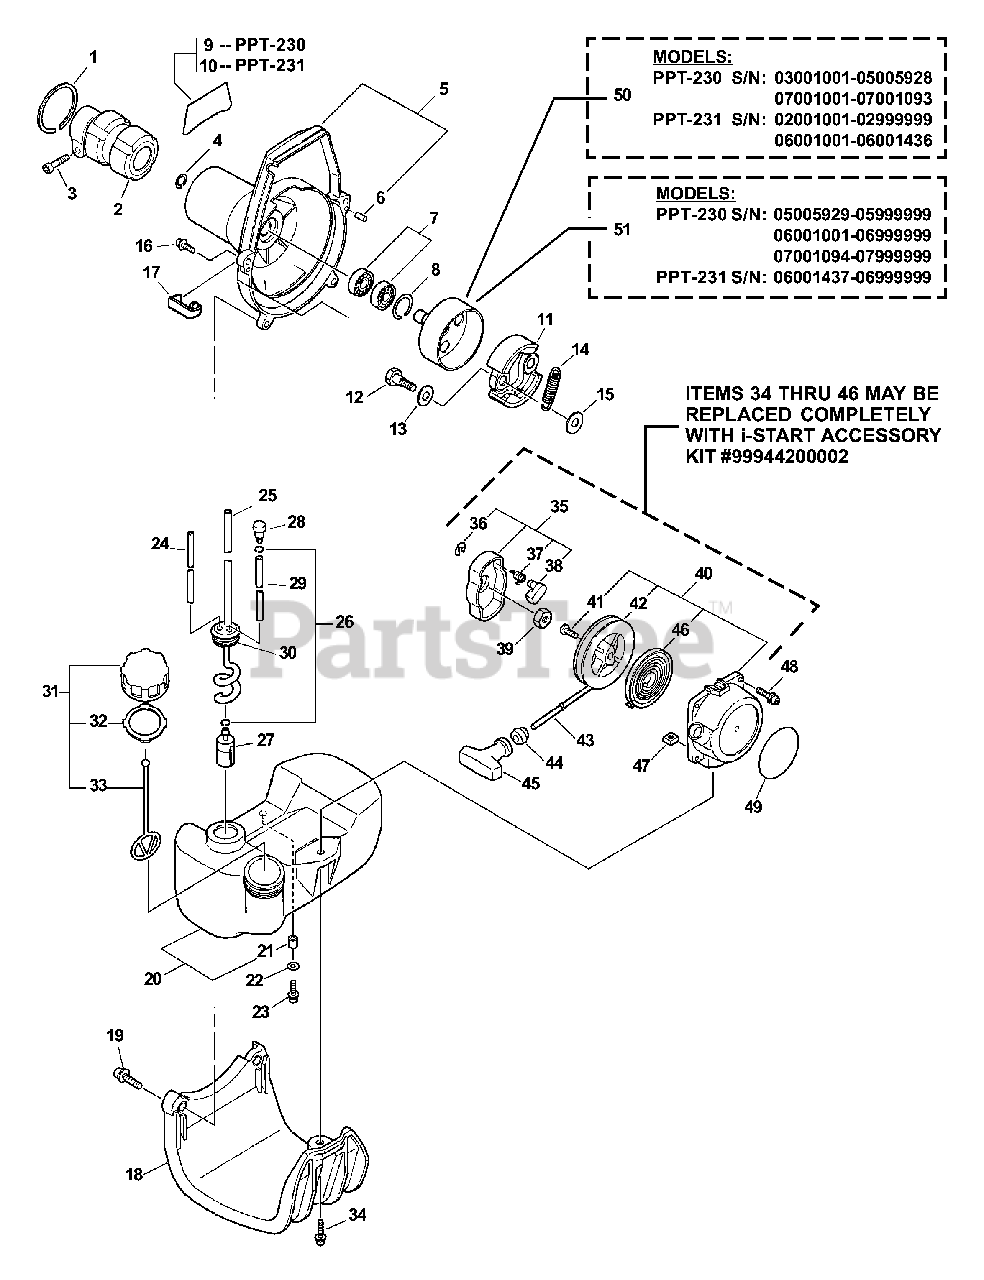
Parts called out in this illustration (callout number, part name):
1	RING, SNAP Ø42
2	HOLDER, MAIN PIPE
3	BOLT 5×28
4	RING, RETAINING - 12
5	FAN CASE ASSY - ORANGE
6	PIN, LOCATING 4
7	BEARING, BALL 6001
8	RING, SNAP 28
9	LABEL, MODEL
10	LABEL, MODEL
11	SHOE, CLUTCH
12	BOLT, CLUTCH 8×7.9×M6
13	WASHER, SPRING 8.5×16×0.5
14	SPRING, CLUTCH
15	WASHER 6.2×19×1.0
16	BOLT 5×18
18	GUARD, FUEL TANK
19	BOLT 5×22
20	TANK, FUEL
21	SPACER 6.2×7.8×6
22	WASHER 5.5×12×0.8
23	BOLT 5×16
24	PIPE, FUEL 3×6×80 CLEAR
25	PIPE, FUEL 3×6×170
26	CLIP Ø6.5 MM
27	FILTER, FUEL
28	VENT ASSY
29	PIPE 3×6×115 BLACK
30	GROMMET, FUEL
31	CAP ASSY, FUEL
32	GASKET, FUEL CAP
33	CONNECTOR, CAP L= 100 MM
34	SCREW 5×20
35	PAWL ASSY, STARTER
36	E-RING 4
37	SPRING, RETURN
38	PAWL, STARTER
39	NUT 8×1.25
40	STARTER ASSY, RECOIL
41	SCREW
42	REEL, ROPE
43	ROPE, STARTER 3.5×850
44	GUIDE, ROPE
45	GRIP, STARTER
46	SPRING, RECOIL
47	NUT M5
48	BOLT 4×12
49	LABEL - ECHO
50	DRUM, CLUTCH
51	DRUM, CLUTCH
